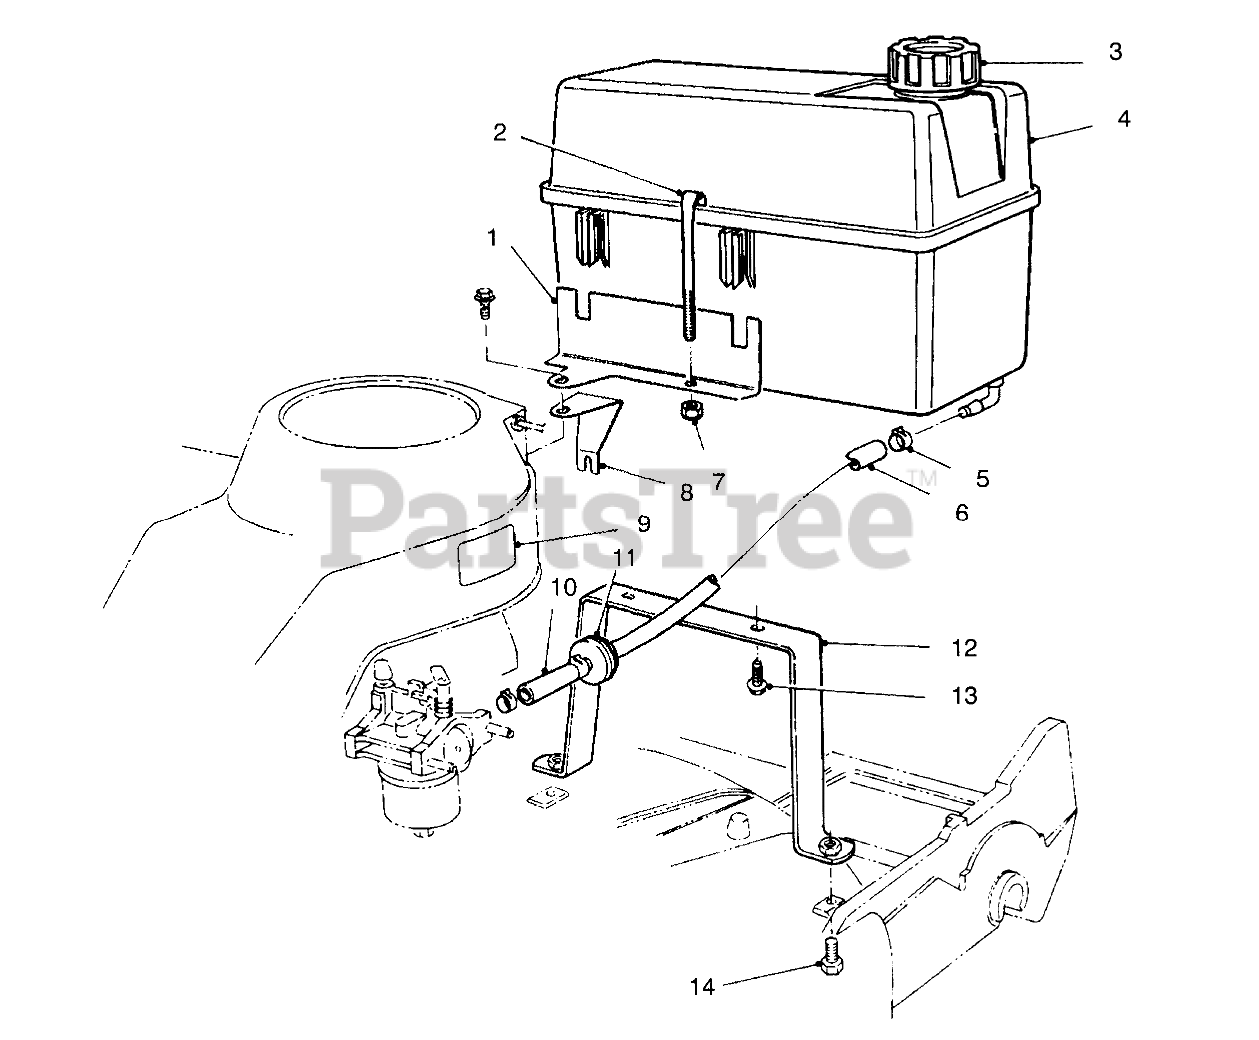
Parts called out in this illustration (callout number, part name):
1	Bracket Tank
2	RETAINER - FUEL TANK
3	GAS CAP ASM
4	Tank-Gas
5	CLAMP-FUEL LINE
6	HOSE-FUEL
7	NUT-LOCK, NI
8	Support-Bracket
9	DECAL-FUEL, 2 CYCLE
10	LINE-GAS
11	FILTER-FUEL
12	Mount-Tank, Bottom
13	SCREW-HWH
14	SCREW-HH
